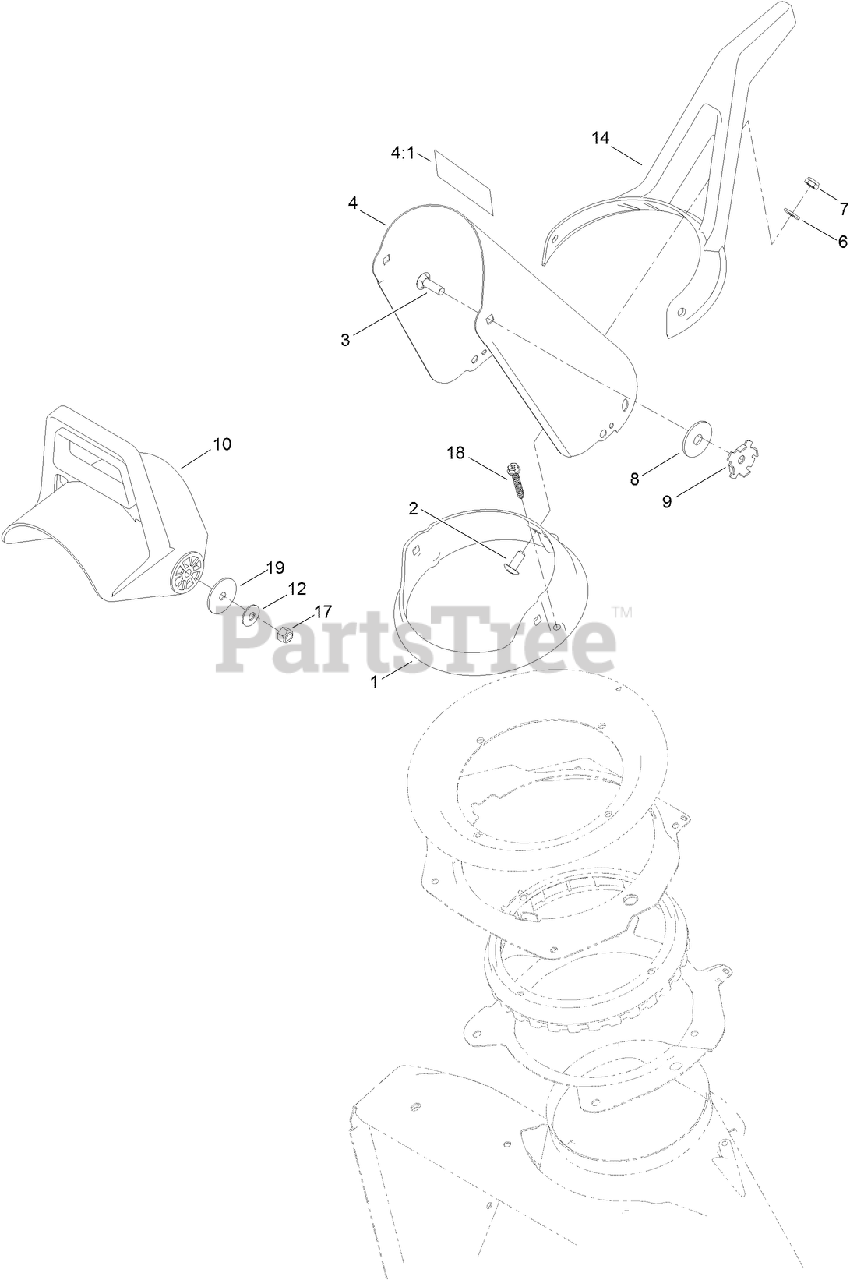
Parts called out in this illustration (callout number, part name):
1	RING-CHUTE
2	SCREW-PTH
3	SCREW-CARR
4	DISCHARGE CHUTE ASM
4:1	DECAL-DANGER, CE
6	WASHER-FLAT
7	NUT-LOCK, NI
8	WASHER-RUBBER
9	PLATE-FRICTION
10	CHUTE-DEFLECTOR
12	WASHER-BELLEVILLE
14	HANDLE-CONTROL, CHUTE
17	NUT-LOCK, NI
18	SCREW-PLASTITE
19	WASHER-FLAT
